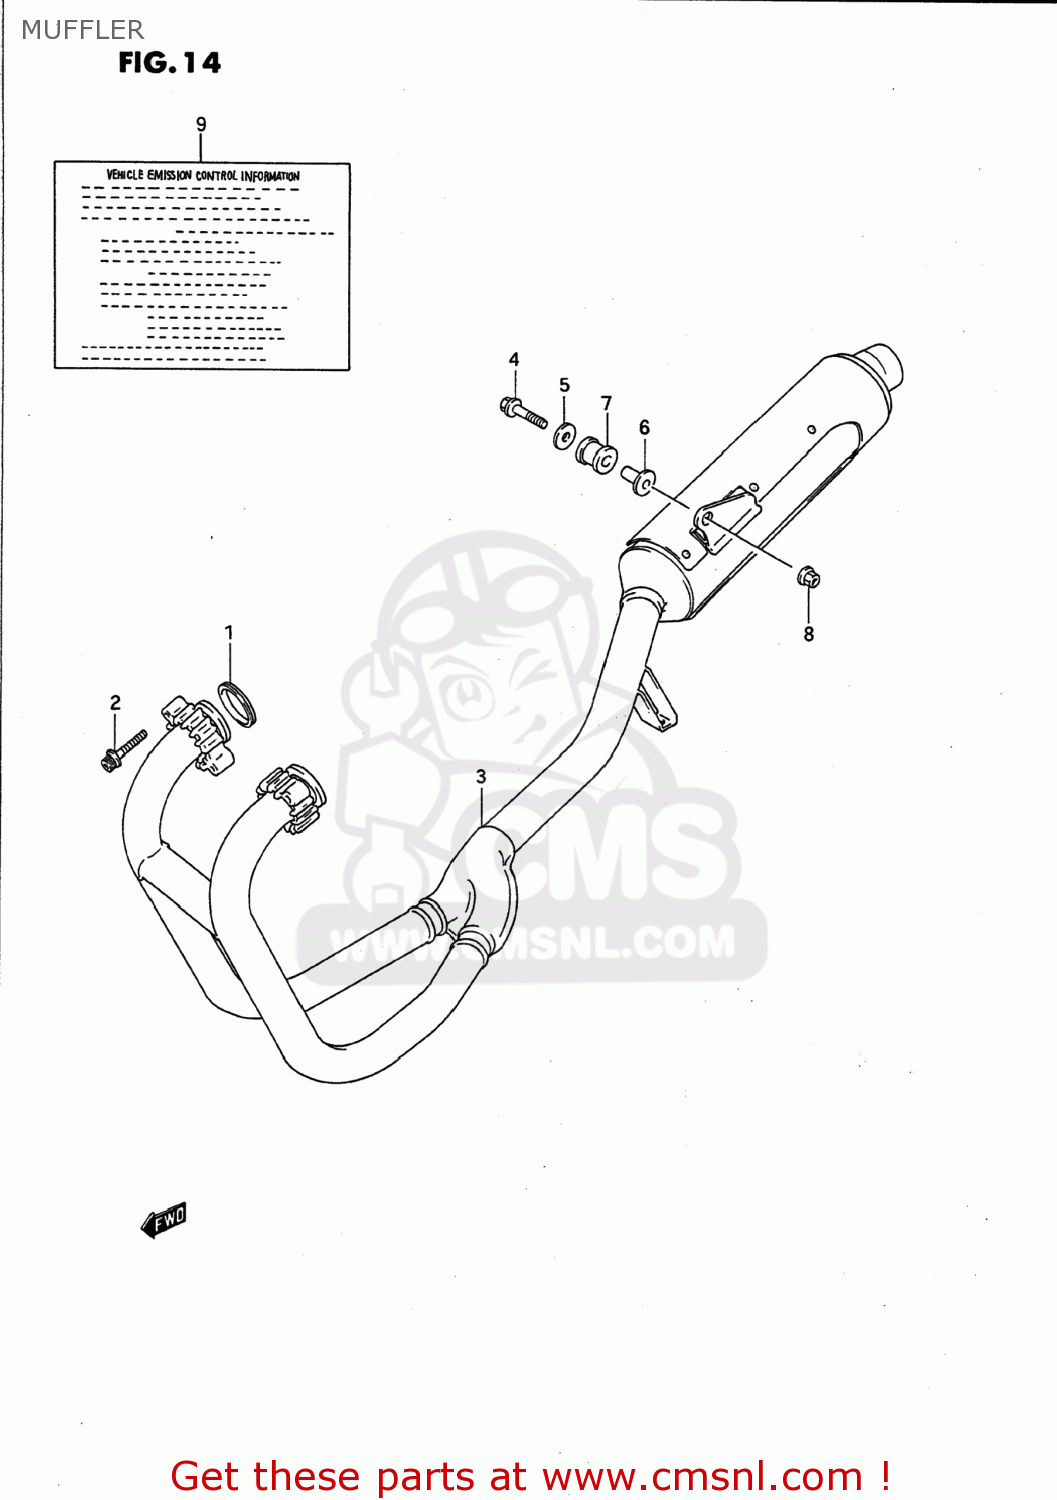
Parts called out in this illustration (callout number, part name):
1	GASKET,EXHAUST PIPE (NAS)
2	BOLT
3	MUFFLER
4	BOLT(8X40)
5	WASHER (8.5X29X1.6)
6	SPACER(8.6X12X24.2)
7	CUSHION
8	NUT
9	LABEL (INFORMATION E3)
